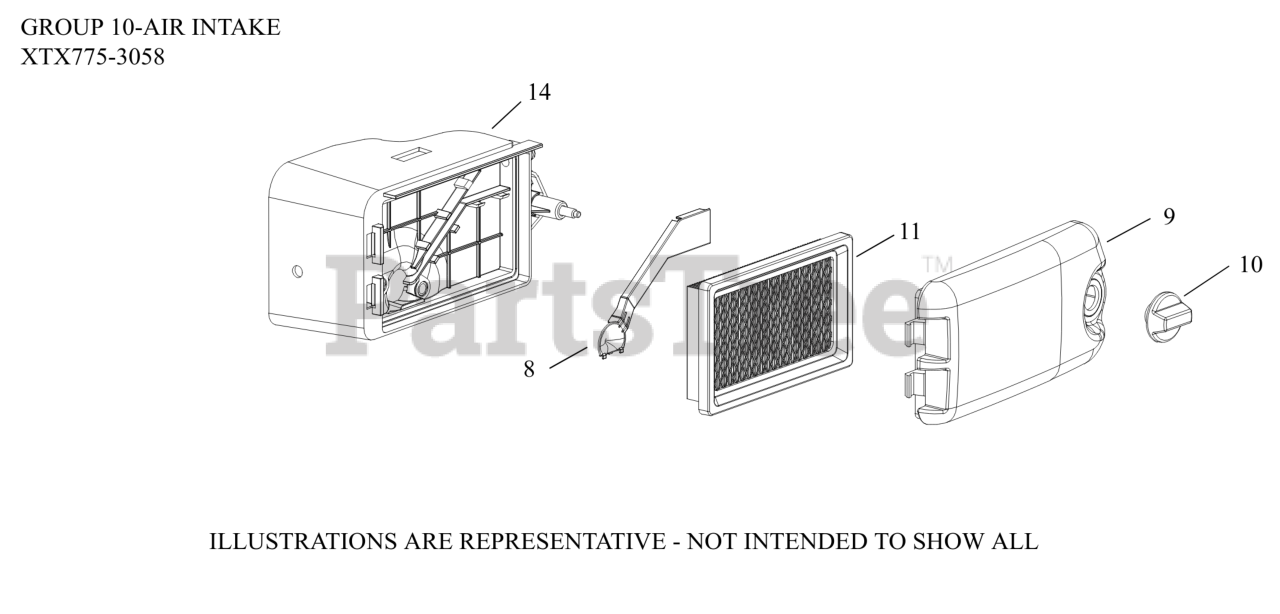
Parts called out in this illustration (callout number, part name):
8	COVER, A/C BASE (BREATHER GAS)
9	COVER, AIR CLEANER
10	KNOB-USE 14 341 07-S
11	ELEMENT, FOAM FILTER
14	BASE, AIR CLEANER - USE 14 094 21-S
